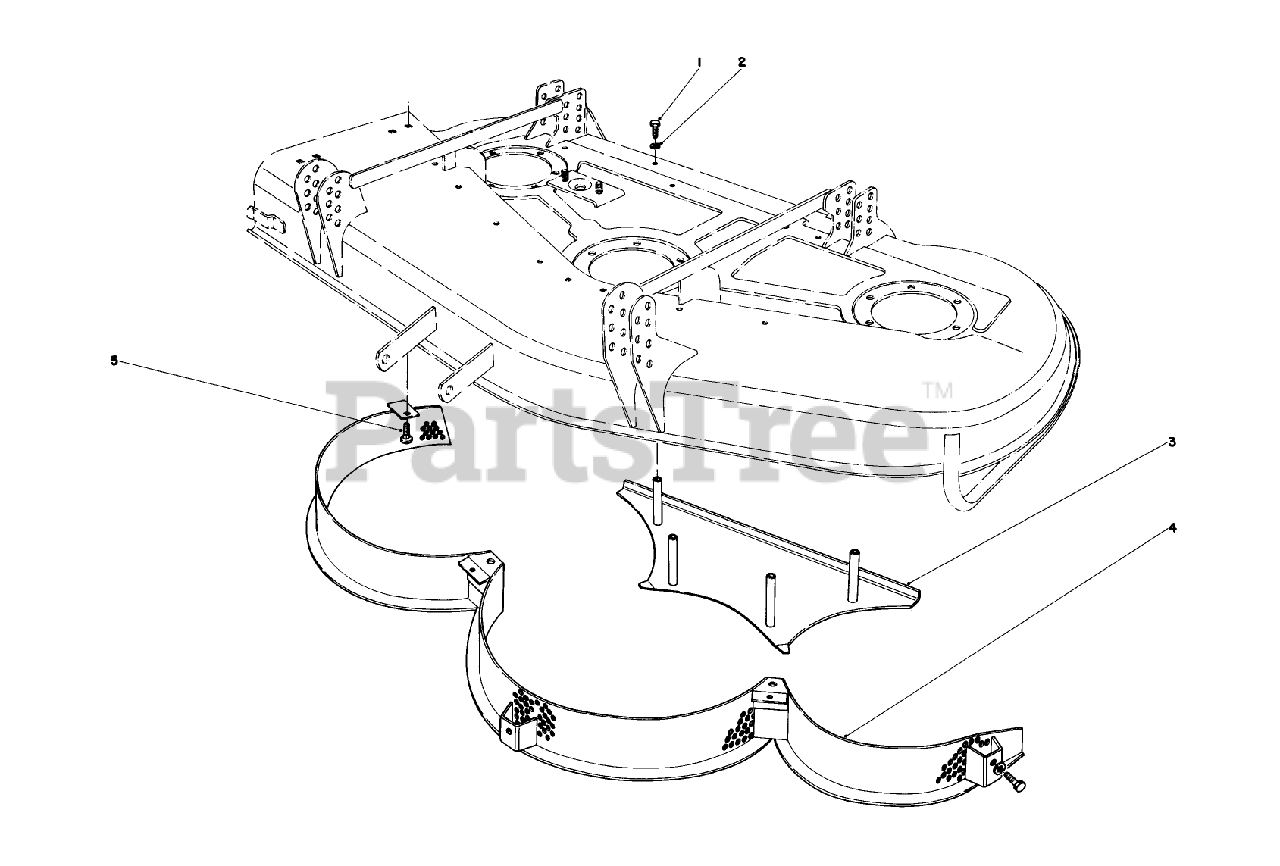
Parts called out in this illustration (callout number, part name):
1	SCREW-HH
2	WASHER-LOCK
3	Bottom Rear Shelf
4	Mulcher Screen
5	BOLT-CARR
